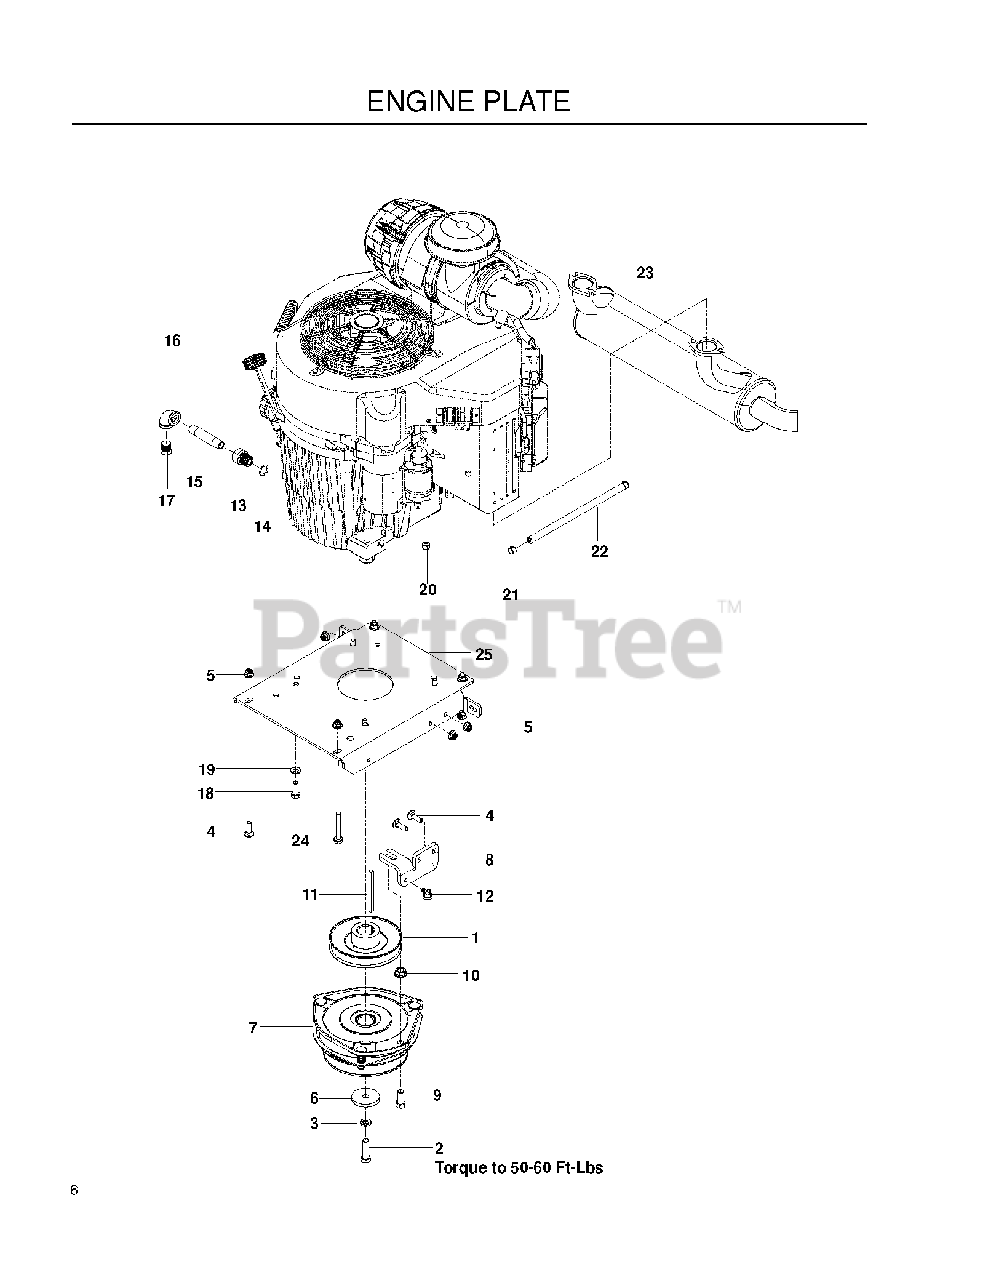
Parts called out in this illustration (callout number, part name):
1	PULLEY, ENGINE
2	HCS 7/16F X 1 1/2
3	WASHER 7/16 LOCK
4	RHSNB 5/16C X 1
5	5/16-18 NYLOC FLANGE NUT
6	BLADE WASHER
7	CLUTCH, GT3.5
8	STOP, CLUTCH, OGURA
9	HCS 7/16-14 X 1 GR 5 ZD
10	NUT 7/16C WHIZ
11	KEY, 1/4 SQ X 3.5
12	TIE WRAP, 8-3/8", W/CLIP
13	ADAPTER, OIL DRAIN
15	PIPE NIPPLE 3/8 X 3
16	90 DEG.ELBOW 3/8NPT
17	PLUG, DRAIN 3/8 NPTF
18	HCS 3/8C X 1
19	WASHER, 3/8 DISC SPRING SPEC
20	NUT M8-1.25 TOP NYL GR10 ZD
21	HOSE CLAMP
22	GAS LINE 10"
23	MUFFLER, 29HP KAW FX751V-850V
23	MUFFLER, 34HP KAW FX921V-1000V
24	HHFS 5/16-18 X 2.25 GD 5
25	PLATE.ENGINE.BLACK
